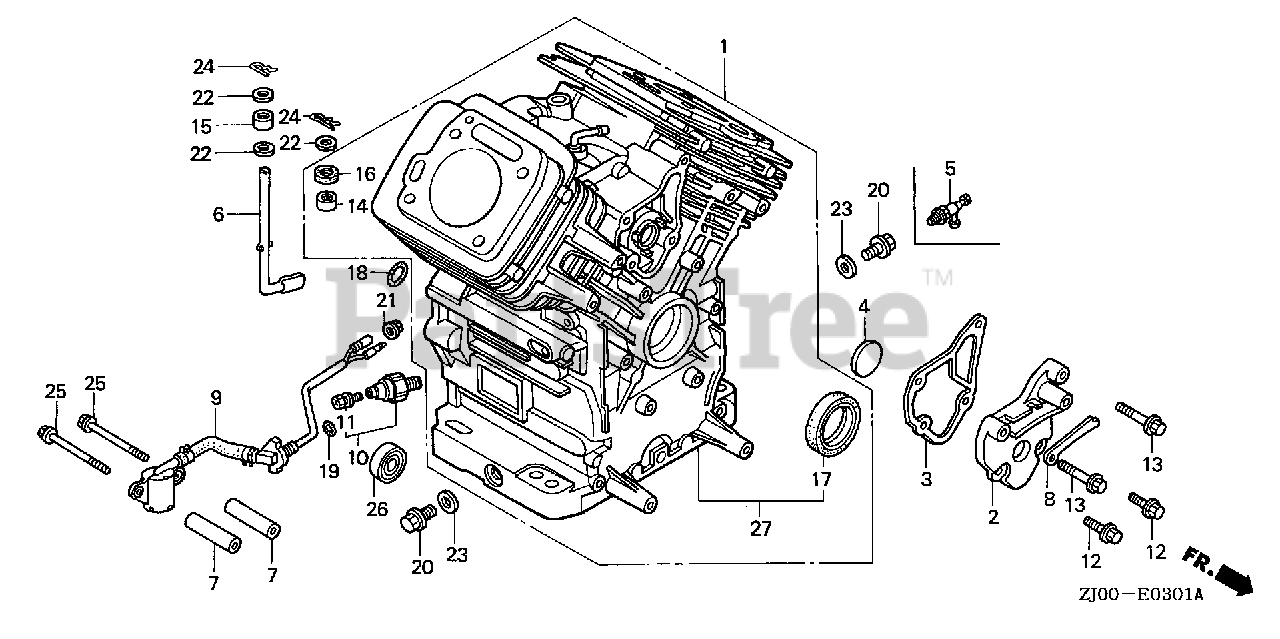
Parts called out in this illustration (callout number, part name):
1	CYLINDER ASSY.
2	COVER, BREATHER
3	GASKET, BREATHER COVER
4	VALVE, BREATHER
5	VALVE, DRAIN (14X1.5)
6	SHAFT, GOVERNOR ARM
7	COLLAR, FILTER SETTING
8	CLAMP, WIRE
9	SWITCH ASSY., OIL LEVEL
12	BOLT, FLANGE (6X16) (CT200)
13	BOLT, FLANGE (6X32) (CT200)
14	BEARING, NEEDLE (8X12.7X11.1)
15	BEARING, NEEDLE (8X12X10)
16	OIL SEAL (8X14X5)
17	OIL SEAL (38X58X9)
18	O-RING (13X3.0)
19	O-RING (13.5X1.5) (ARAI)
19	O-RING (14MM) (NOK)
20	BOLT, DRAIN PLUG (14MM)
21	NUT, FLANGE (10MM)
22	WASHER, PLAIN (8MM)
23	WASHER, DRAIN PLUG (14MM)
24	PIN, LOCK (8MM)
25	BOLT, FLANGE (6X75)
26	BEARING, RADIAL BALL (6003)
